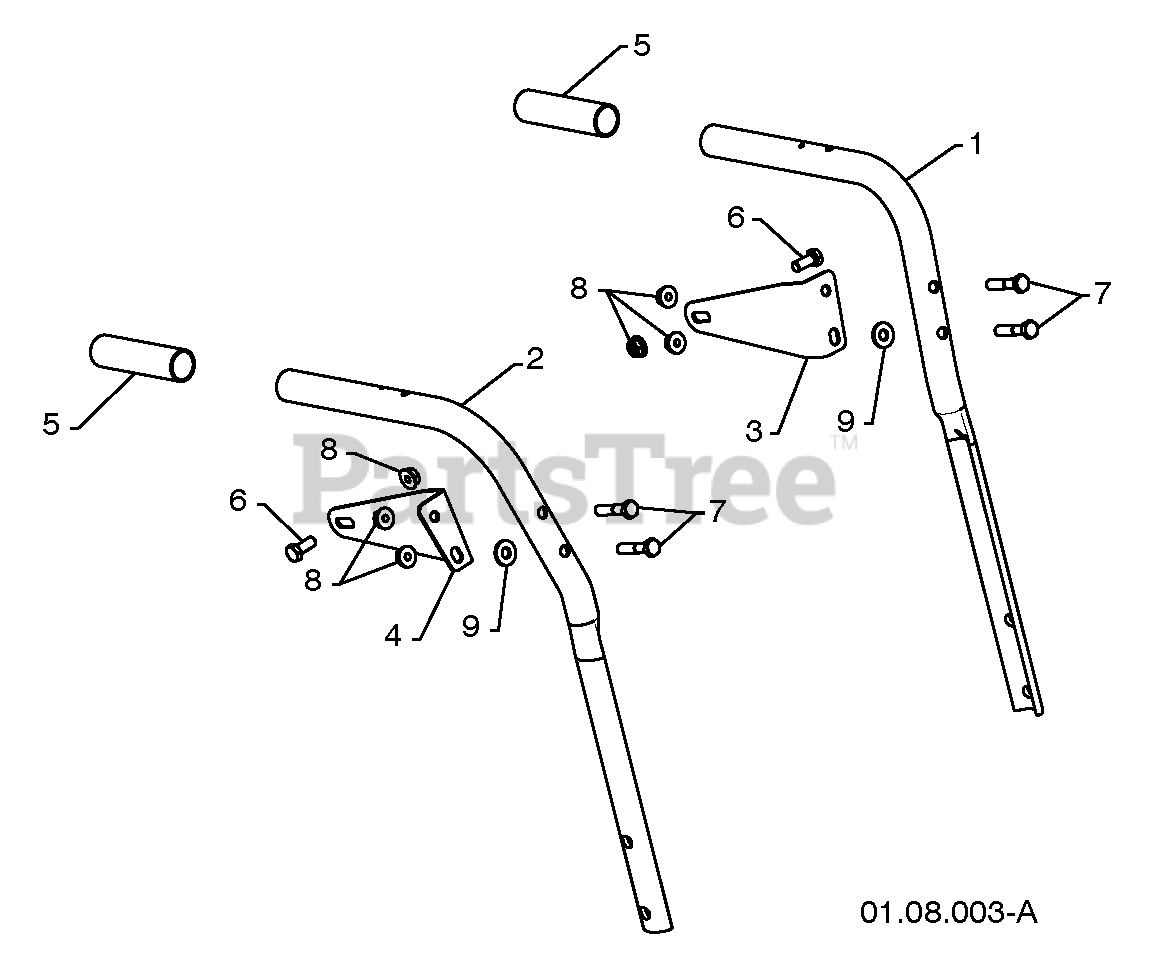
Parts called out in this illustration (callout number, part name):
1	PLOW HANDLE LH
2	PLOW HANDLE RH
3	PANEL BRACKET LH
4	PANEL BRACKET RH
5	HANDLE GRIP
6	SCREW 5/16-18 X .750
7	SCREW 5/16-18 X 1.50
8	NUT 5/16-18
9	WASHER
